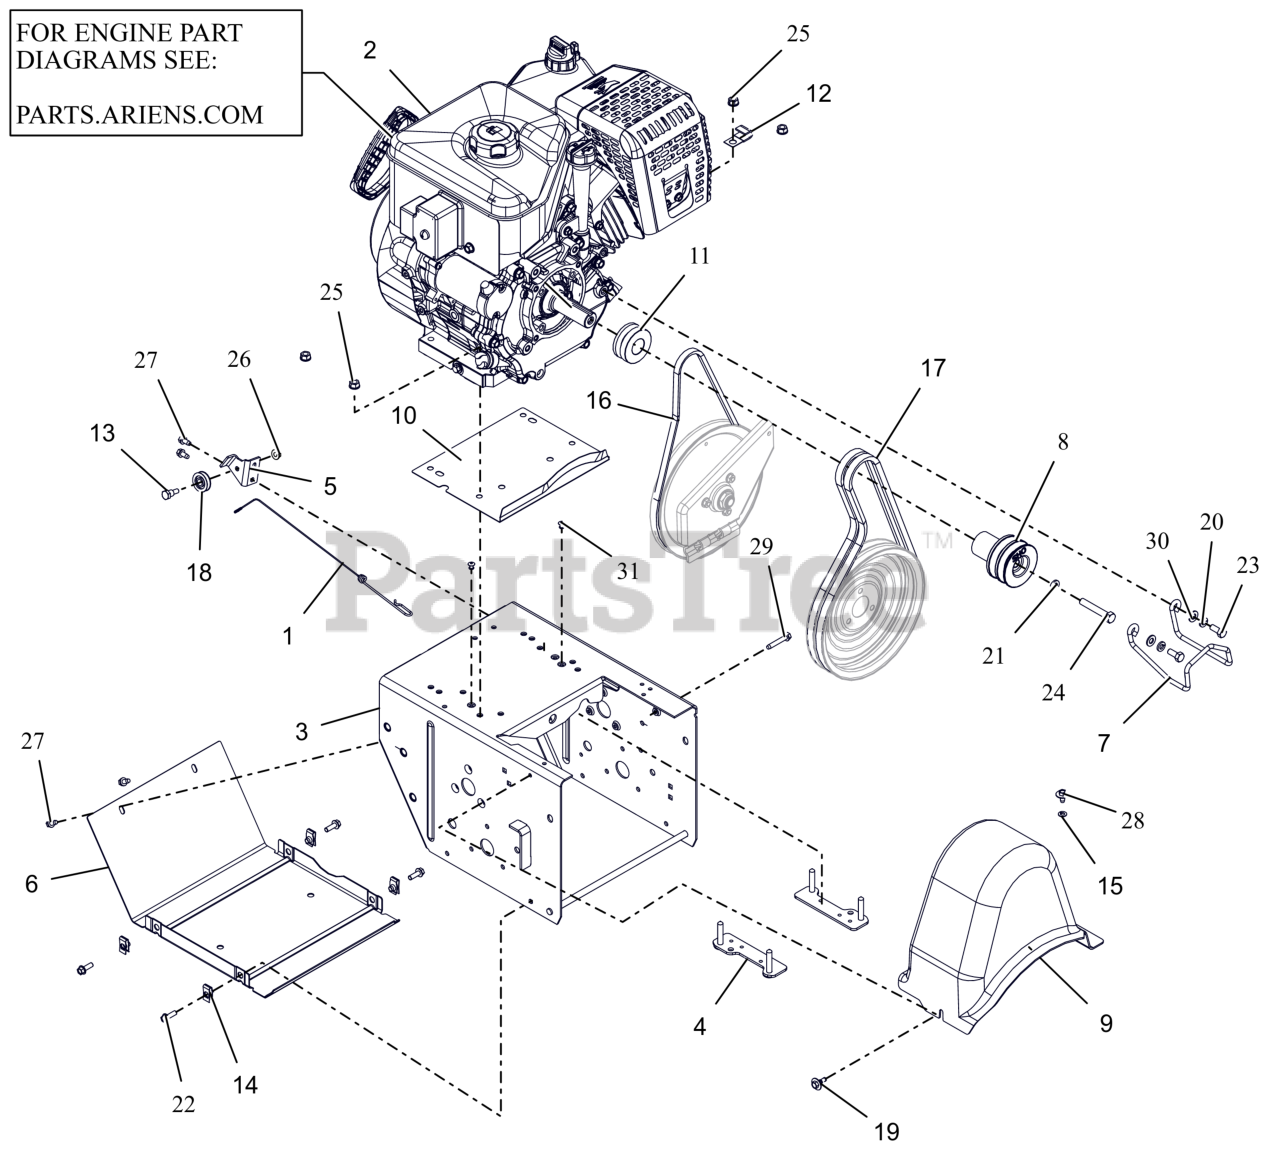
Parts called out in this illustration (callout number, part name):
1	CABLE, LOWER TRACTION,SS & PRO
2	ENGINE, AX420 GEN 3 240V/60W
3	FRAME, MAIN - PRO (WELDMENT)
4	STRAP, BOLT-LARGE
5	BRACKET, CABLE PULLEY
6	COVER, BOTTOM
7	FINGER, BELT
8	SHEAVE,ATTACHMENT-SHO 2 GRV
9	COVER, BELT-LARGE
10	BAFFLE, WATER - LARGE BLOCK
11	SHEAVE, TRACTION (KEYLESS)
12	J-CLAMP
13	BOLT, SHLDR -.375 X .375 X .25-20
14	NUT-RTNR .25-20X.56
15	NUT-PUSH .25X.50 O.D.
16	V-BELT, 3L-WRAPPED
17	V-BELT, HA-RAW EDGE (SET)
18	PULLEY, CABLE
19	SCR-TAP .25-20X.5 CAPTIVE
20	WSHR, LK-HVY .312X.097 ZCC
21	WSHR,LK-REG .375X.094 ZCC
22	BLT, HWH .25-20X.75 G5 ZCC
23	BLT, HEX .31-24X.750 G5 ZCC
24	BLT, HEX .38-24X2.25 G5 ZCC
25	NUT,LK-CTR-FLG .31-18 GF ZCC
26	NUT-LK-TOP-FLG .250-20 GF ZCC
27	SCR-TAP .25-20X.50 HWH ZCC
28	SCR, TAP .25-20X.50 LG HWH ZCC
29	SCR,TAP .25-20X1.50 HWH TR ZCC
30	WSHR,FLT .344X.688X.065 ZCC
31	RVT, POP .1875 ZCC
